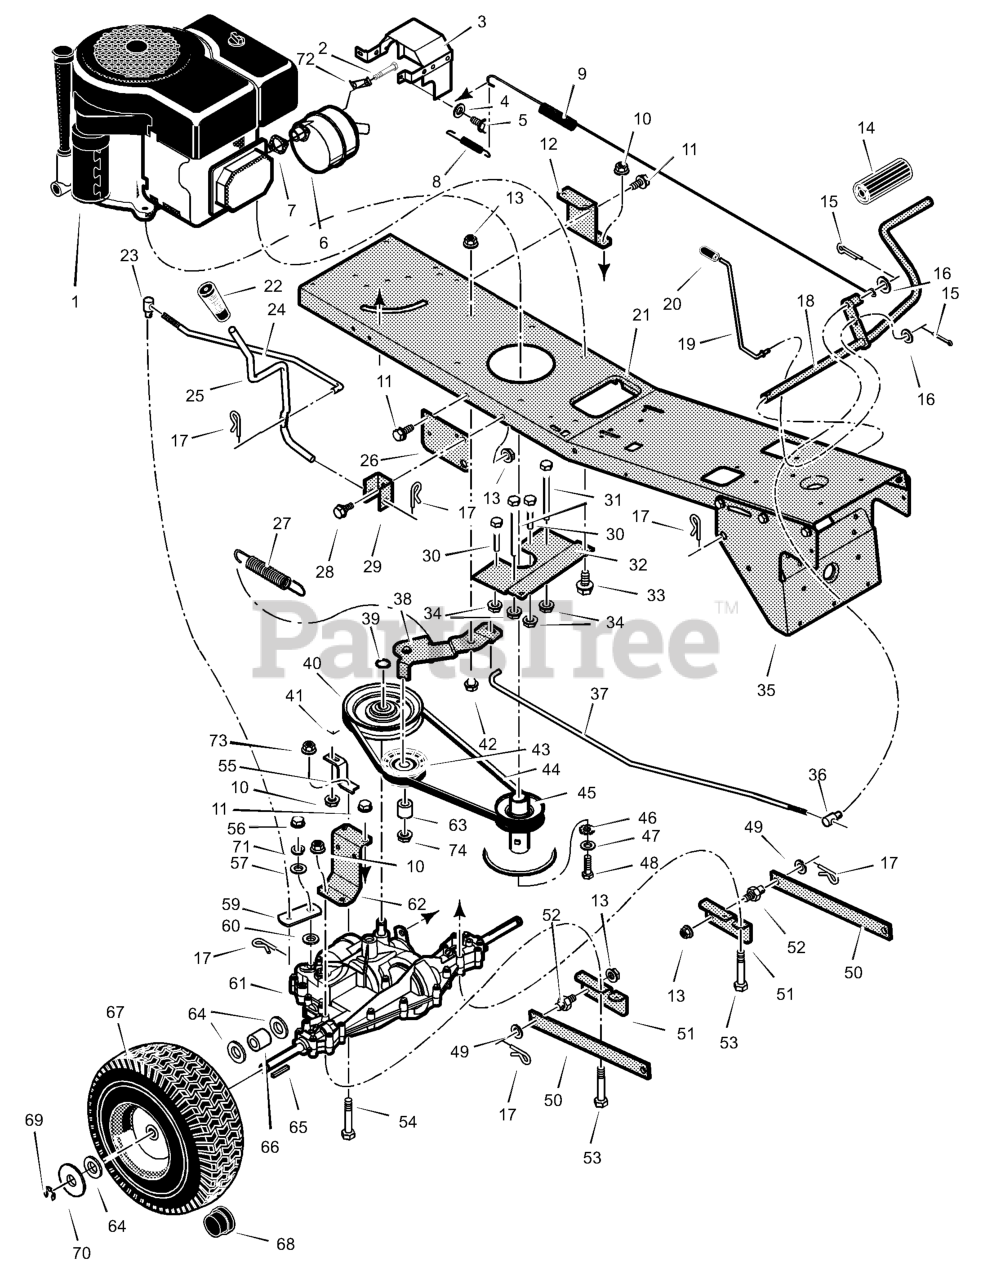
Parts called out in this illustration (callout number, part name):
1	Engine
2	Bolt, Hex
3	Shield Assembly, Heat
4	Lockwasher
5	Screw
6	Muffler Assembly
7	GASKET, Exhaust
8	Spring, Extension
9	Spring, Extension
10	Nut
12	Bracket, Left Transaxle
13	Nut, Flange
14	Cover, Pedal
15	Pin, Cotter
17	Pin, Cotter
18	Pedal Assembly
19	Rod, Parking Brake
20	Grip, Parking Brake Rod
22	Grip, Shift Lever
23	Nut, Adjusting
24	Link, Shift
25	Lever, Shift
26	Bracket, Lift Pivot
27	Spring, Extension
28	Bolt, Shoulder
29	Bracket, Pivot
30	Guide, Short Belt
31	Guide, Long Belt
32	Plate, Belt Guide
33	Bolt
34	Nut, Flange
35	Bracket, Support
36	Nut, Adjusting
37	Rod, Clutch
38	Clutch Arm Assembly
39	Ring, Retainer
40	Pulley, Drive
41	Bolt, Carriage
42	Bolt, Shoulder
43	Pulley, Idler
44	Belt, Motion Drive
45	Pulley, Split Stack
46	Washer, Star
48	Bolt, Hex
49	Washer
51	Bracket, Rear Hanger
52	Pin, Threaded Shoulder
53	Bolt, Hex
55	Bracket, Torque Reactor
57	Washer, Shift Yoke
59	Yoke, Shift
61	Transaxle, Peerless **
62	Bracket, Transaxle
65	Key, Square
66	SPACER, Rear Wheel
67	Wheel, Rear -15" *
68	Cap, Hub
71	Lockwasher, Split
72	Lock, Screw
73	Locknut
74	Locknut
